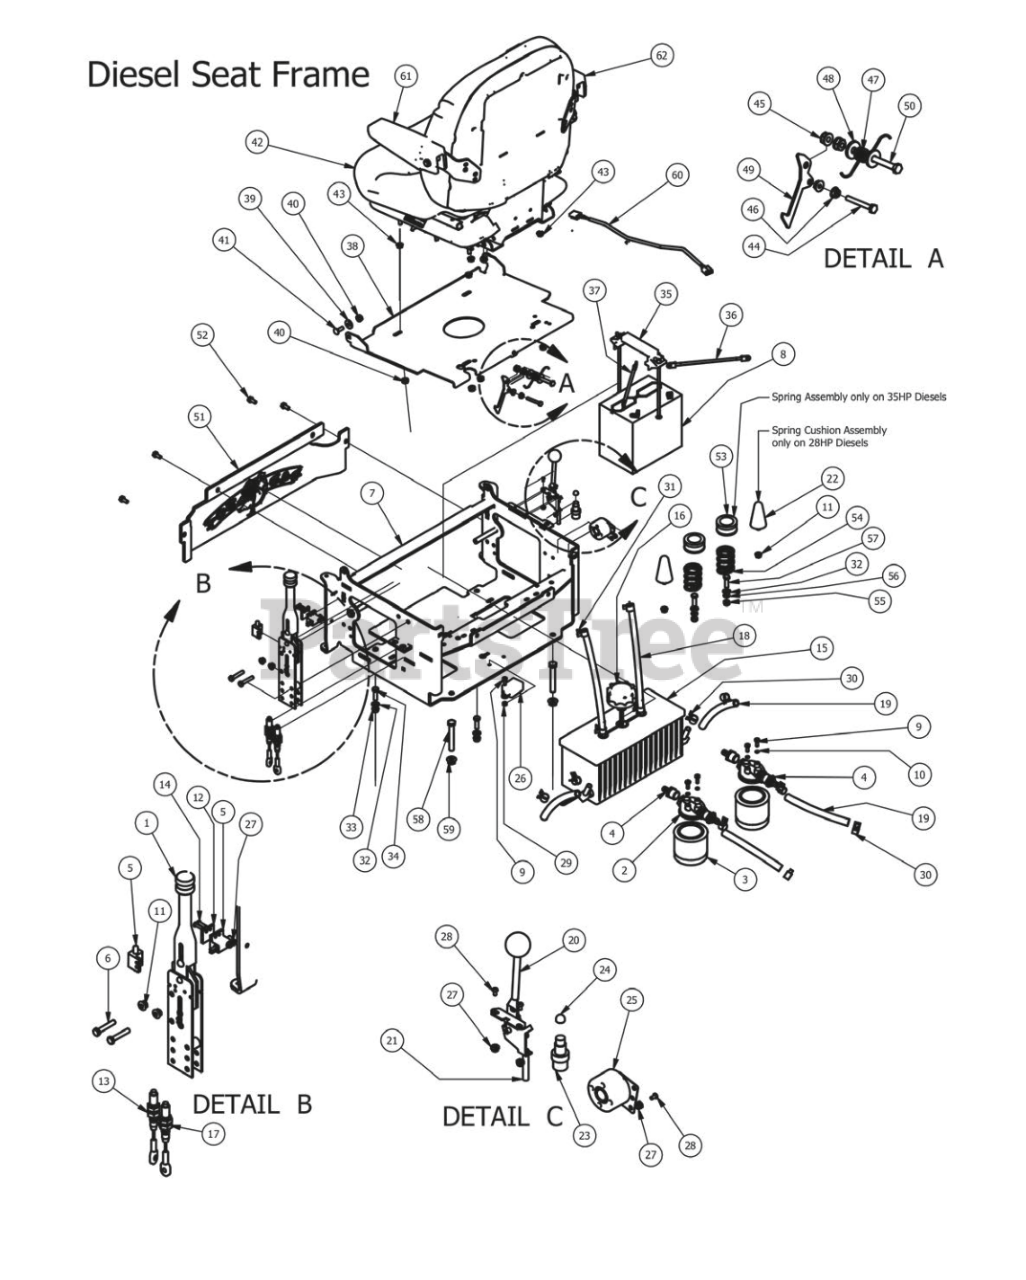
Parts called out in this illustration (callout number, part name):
1	Hand Brake Assembly
2	Filter Head
3	Hydraulic filter
4	Filter Head Fitting
6	5/16" x 1 3/4" Hex Bolt
7	2007 Diesel Seat Frame
8	Battery Diesel Models - 151
9	1/4" x 3/4" Hex Bolt
10	1/4" Lock Washer
11	5/16" Flange Nut
12	Switch Block Plastic
13	Short Brake Cable
14	1024 x 1" Allenhead Bolt
15	Aluminum Hydraulic Tank
16	Hydraulic Tank Cap
17	Long Brake Cable
18	3/8" x 32" Clear Hose
19	1/2" x 9 1/4" Braided Hose
20	Universal Throttle Head-2012
21	Diesel Throttle Cable Only
22	Spring Cushion
23	Momentary Start Switch
24	Start Switch Boot - Diesel
25	Heat Warning Piezo Buzzer
26	Auto Shut Down for Cat Diesels
27	#10 Nylock Nut
28	1024 X 5/8" Buttonhead Bolt
29	1/4" Hex Nut
30	1/2 Hose Clamp
31	3/8 hose clamp
32	3/8" Flat Washer
33	3/8" Flange Nut
34	3/8" x 1 1/4" Hex Bolt
35	Battery Hold Down
36	Black Battery Cable - Diesel
37	Red Battery Cable - Diesel
38	2006 Seat Plate
39	.360 ID Plastic Washer
40	5/16-18 Nylon Flange Nut
41	5/16" x 1" Carriage Bolt
42	Grammer Suspension Seat
43	5/16" Flange Nut
44	1/4-20 x 2 Hex Bolt
45	5/16-18 Nylon Flange Nut
46	1/4-20 Hex Flange Nuts Zinc w/Serrations
47	Torsion Spring for Seat latch
48	.360 ID Plastic Washer
49	Seat Latch Lever
50	5/16-18 X 2 Hex C/S (GR.5) ZC
51	Cooler Cover
52	5/16 x 3/4 washer head type F screw
53	Seat Spring Cap Cover
54	Seat Spring
55	3/8" Hex Nut
56	3/8" Lock Washer
57	3/8" x 1 1/2" Hex Bolt
58	1/2 x 3 1/2 Flange Bolt Grade 8
59	1/2" Flange Nut
60	Seat Switch Adapter
61	Left Armrest Kit-Grammer Seat
62	Right Armrest Kit-Grammer Seat
